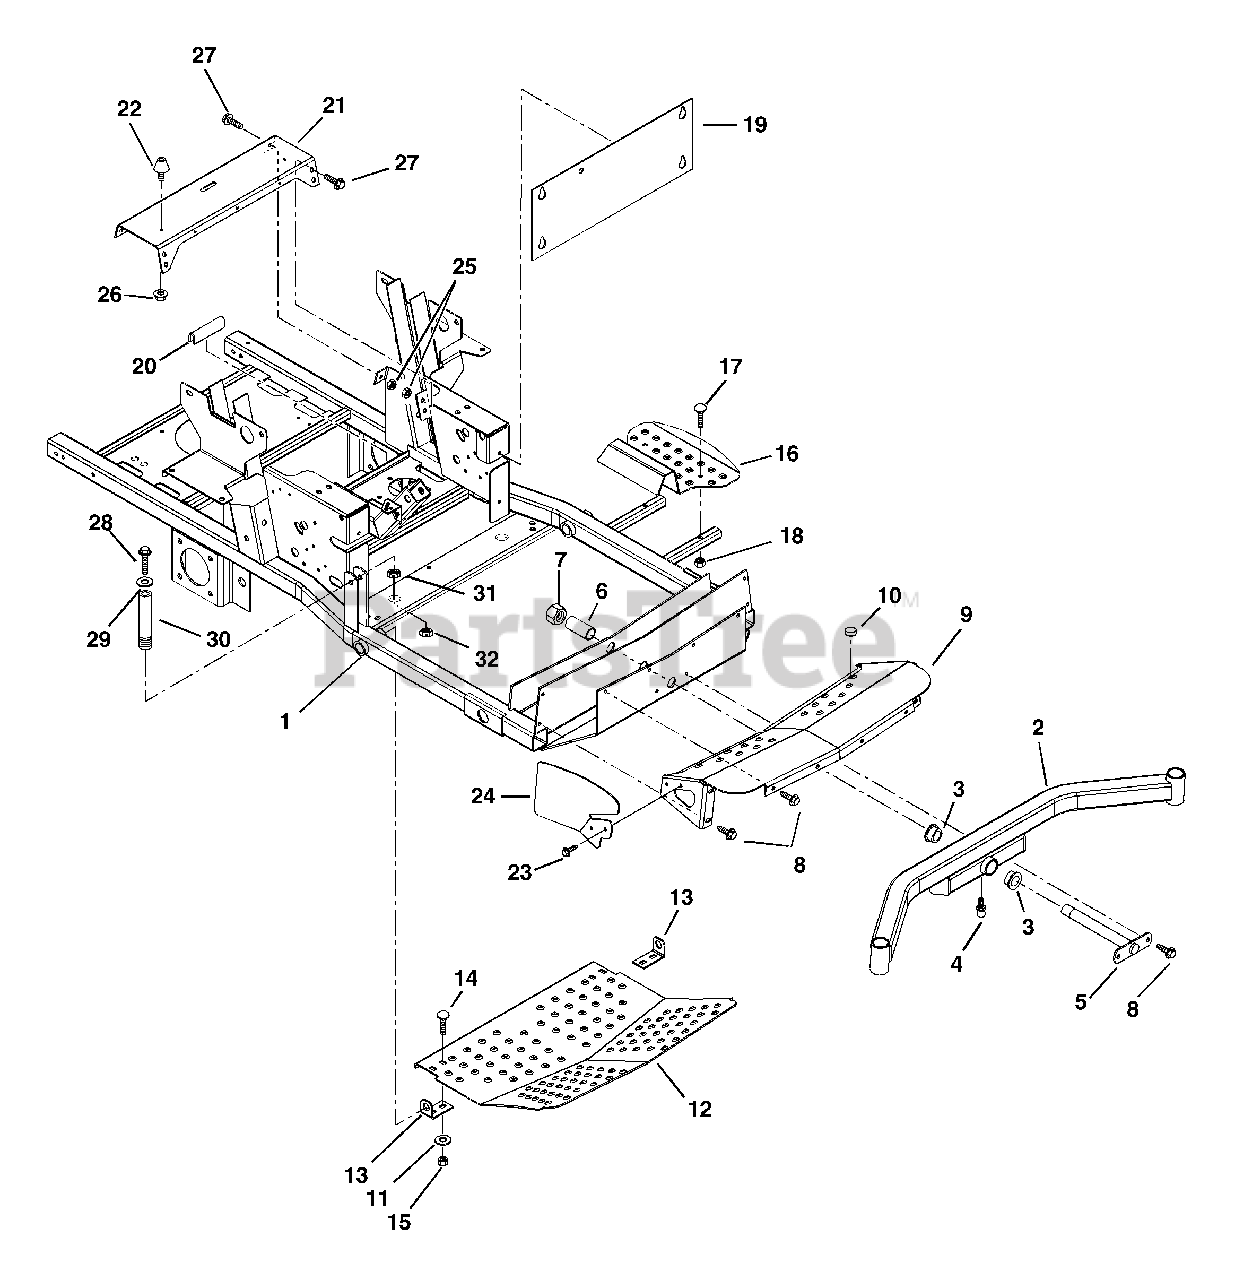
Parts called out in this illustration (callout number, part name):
1	Frame
2	Axle-Front
3	Bushing-Flange 1.020 x 1.385 x .75 x 1.75
4	Fitting-Lube .25 - 28 x .256
5	Pin-Axle
7	Nut-Locking-Nylon 1.0 - 14
8	Screw-Tapping .38 - 16 x .75
9	Cover-Axle
10	Button Bumper
11	Washer-Flat-Steel .38 x .875 x .083
12	Panel-Inspection
13	Mount-Inspection Panel
14	Bolt-Round Head Square Neck .38 - 16 x 1.00 Grade 5
15	Nut-Locking-Nylon .38 - 16
16	Step-Ingress
17	Bolt-Round Head Square Neck .31 - 18 x 1.50 Grade 5
18	Nut-Locking-Center .31 - 18
19	Plate-Kick
20	Strip-Cowl
21	Channel-Cross
23	Screw-Tapping .25 - 20 x .50 Hex Washer Head
24	Cover, Cylinder Rod End
25	Nut-Retainer .375 - 16 x .37
26	Nut-Locking-Flange .312 - 24
27	Bolt-Serrated Flange Washer Head .38 - 16 x 1.00
28	Bolt-Hex .50 - 20 x 1.00 Grade 5
29	Washer-Flat-Steel .531 x 1.06 x .095
30	Post
31	Nut-Jam .75 - 16
32	Nut, Jam Center-Lock .75 - 16
